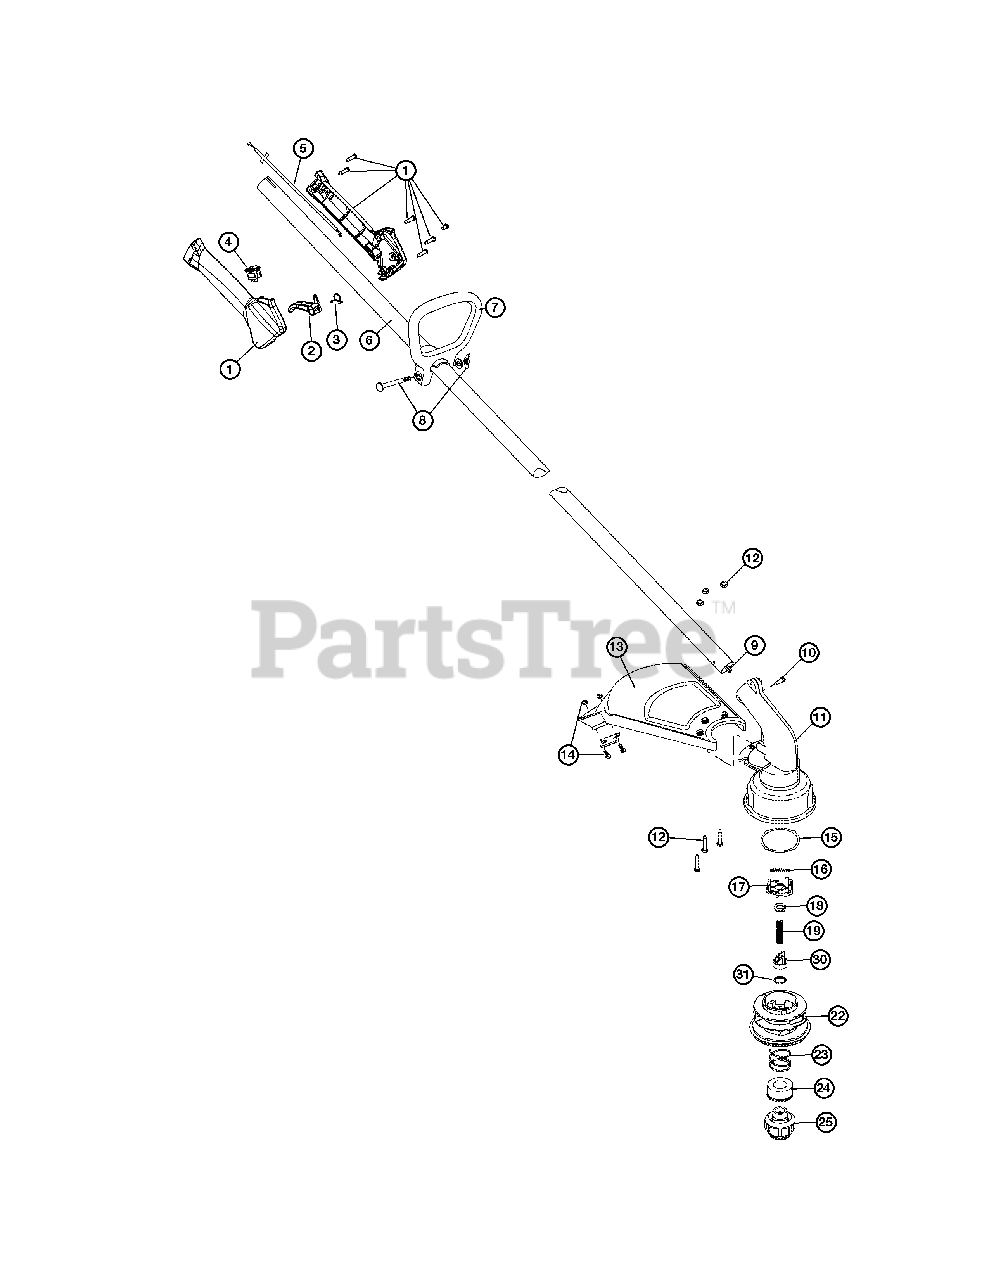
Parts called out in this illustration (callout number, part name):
1	Throttle Housing Assembly
2	Throttle Trigger
3	Throttle Trigger Spring
4	Switch Assembly
5	Throttle Cable Assembly
6	Drive Shaft Housing
7	D-Handle Assembly
8	D-Handle Hardware
9	Flexible Drive Shaft
10	Anti-Rotation Screw
11	Gear Box Assembly
12	Shield Mounting Hardware
13	Shield Assembly
14	Blade Assembly
15	Thrust Washer
16	Slider
17	Small Spring
20	Plunger
22	Inner Reel
23	Large Spring
24	Foam Seal
25	Bump Knob Assembly
